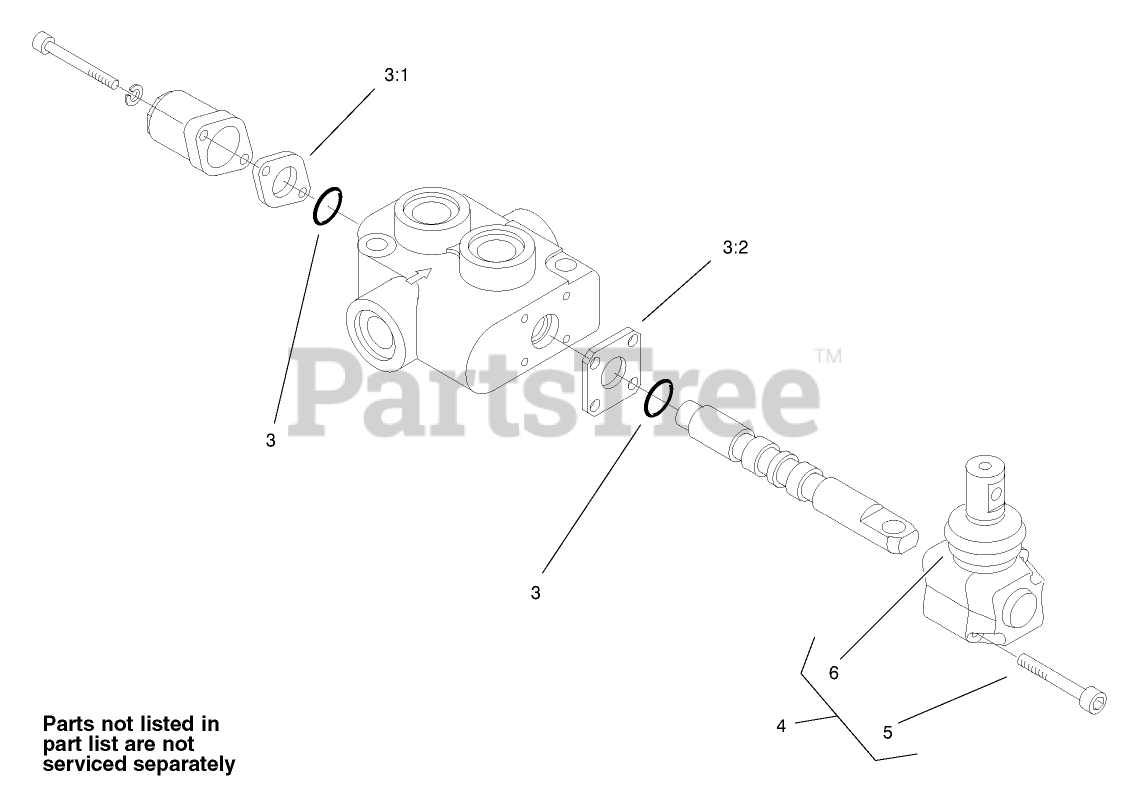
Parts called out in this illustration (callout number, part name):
3	SEAL KIT
3:1	GASKET
3:2	GASKET
